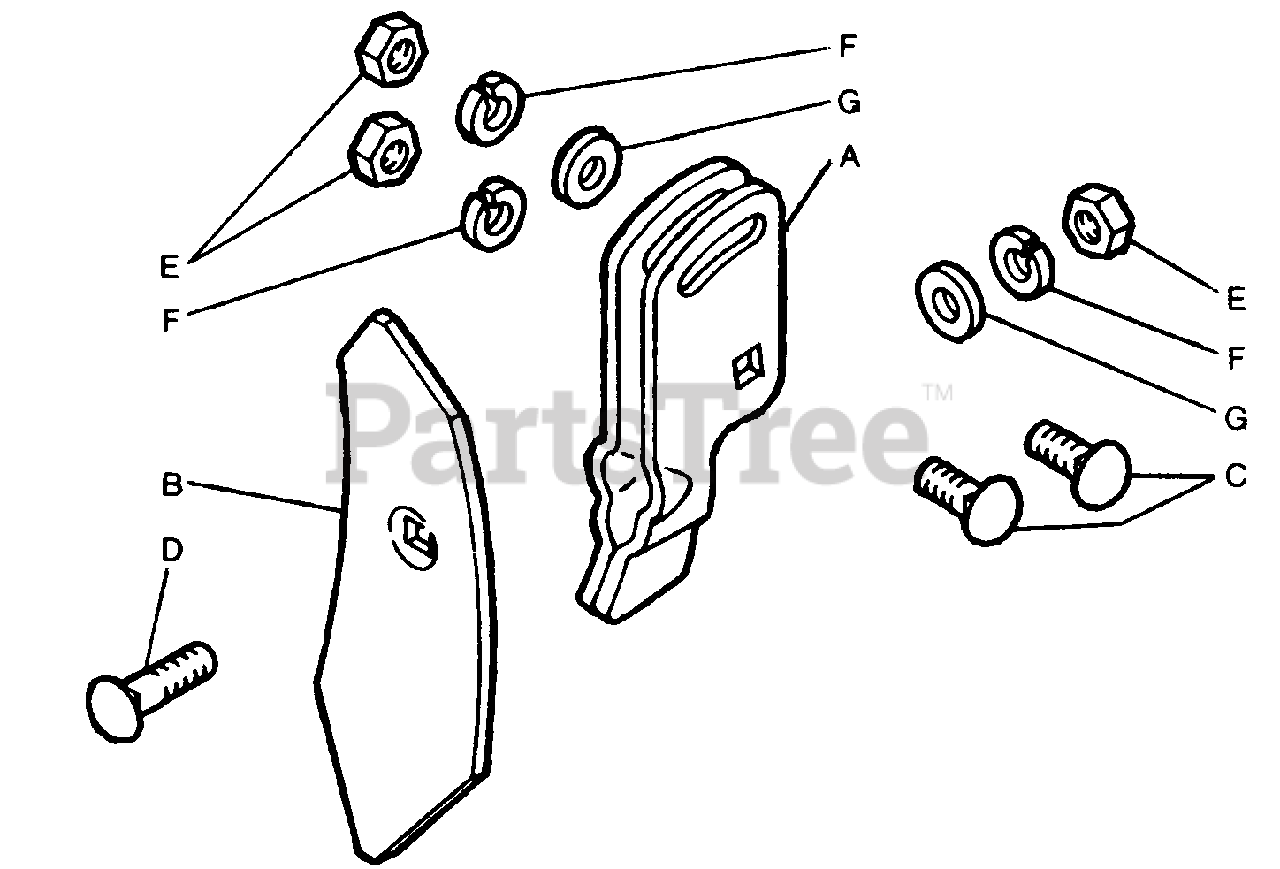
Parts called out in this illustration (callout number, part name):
A	Holder Assembly
B	Shovel
C	Bolt, Carriage 3/8-16 x 1 1/4 Plated
D	Bolt, Plow 3/8-16 x 2 Plated
E	Nut, Hex 3/8-16 Plated
F	Washer, Lock 3/8 Plated
G	Washer, Flat 3/8 Plated
